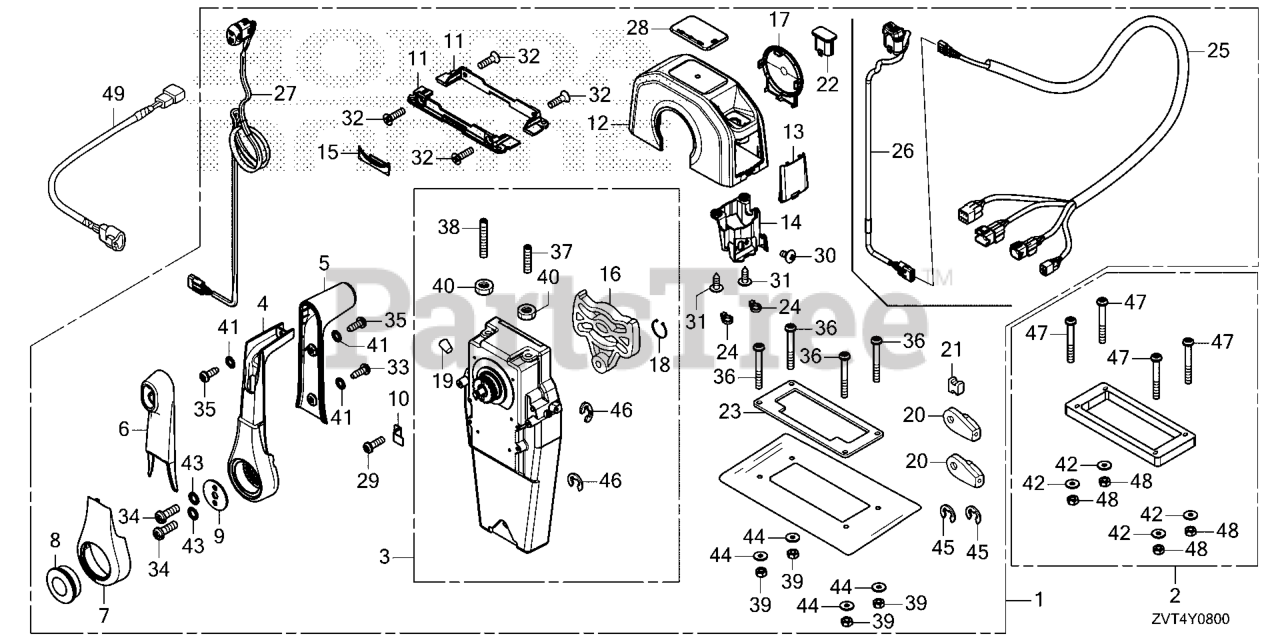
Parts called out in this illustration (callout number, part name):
1	BOX KIT, R/C
2	SPACER KIT, REMOTE CONTROL BOX (TOP MOUNT SINGLE)
3	HOUSING ASSY., L. (INNER) (TOP MOUNT) (NOT AVAILABLE)
4	HANDLE, REMOTE CONTROL (NOT AVAILABLE)
5	COVER, GRIP
6	GRIP
7	COVER, LEVER (NOT AVAILABLE)
8	BUTTON, THROTTLE (NOT AVAILABLE)
9	PLATE, HANDLE
10	PLATE, CABLE CLAMP
11	BRACKET, REMOTE CONTROL HOUSING (NOT AVAILABLE)
12	HOUSING, SINGLE REMOTE CONTROL BOX (NOT AVAILABLE)
13	PLUG, SINGLE HOUSING (NOT AVAILABLE)
14	GUIDE, SINGLE WATER (NOT AVAILABLE)
15	HOUSING, LEAD (NOT AVAILABLE)
16	PLATE, DWELL
17	COVER, HOUSING SIDE (NOT AVAILABLE)
18	RING, SNAP (NOT AVAILABLE)
19	GROMMET (NOT AVAILABLE)
20	TERMINAL, CABLE
21	SPACER, CABLE CLAMP
22	CAP, BLANK (NOT AVAILABLE)
23	GASKET T/S
24	BAND, TY-RAP (POWER TRIM-TILT) (NOT AVAILABLE)
25	HARNESS SUB-ASSY., REMOTE CONTROL (NOT AVAILABLE)
26	SWITCH ASSY., TROLLING CONTROL (NOT AVAILABLE)
27	SWITCH ASSY., POWER TRIM-TILT (NOT AVAILABLE)
28	MARK, REMOTE CONTROL (SINGLE) (NOT AVAILABLE)
29	SCREW, PAN (5X16)
30	SCREW, TRUSS (5X10) (NOT AVAILABLE)
31	SCREW, TRUSS (5X16) (TAPPING) (NOT AVAILABLE)
32	SCREW, PAN (5X18)
33	SCREW, PAN (5X14) (TAPPING) (NOT AVAILABLE)
34	SCREW, PAN (6X18)
35	SCREW, PAN (5X14) (TAPPING)
36	SCREW, PAN (5X40)
37	BOLT, STOPPER (F) (NOT AVAILABLE)
38	BOLT, STOPPER (R) (NOT AVAILABLE)
39	NUT, HEX. (5MM)
40	NUT (6MM) (LOOSE PARTS)
41	WASHER, LOCK (5MM)
42	WASHER, PLAIN (5MM)
43	WASHER, LOCK (6MM)
44	WASHER, PLAIN (5MM)
45	E-RING (6MM) (LOOSE PARTS)
46	E-RING (6MM) (LOOSE PARTS)
47	SCREW, PAN (5X65)
48	NUT, HEX. (5MM)
49	SUB-HARNESS ASSY., POWER TRIM-TILT (A)
